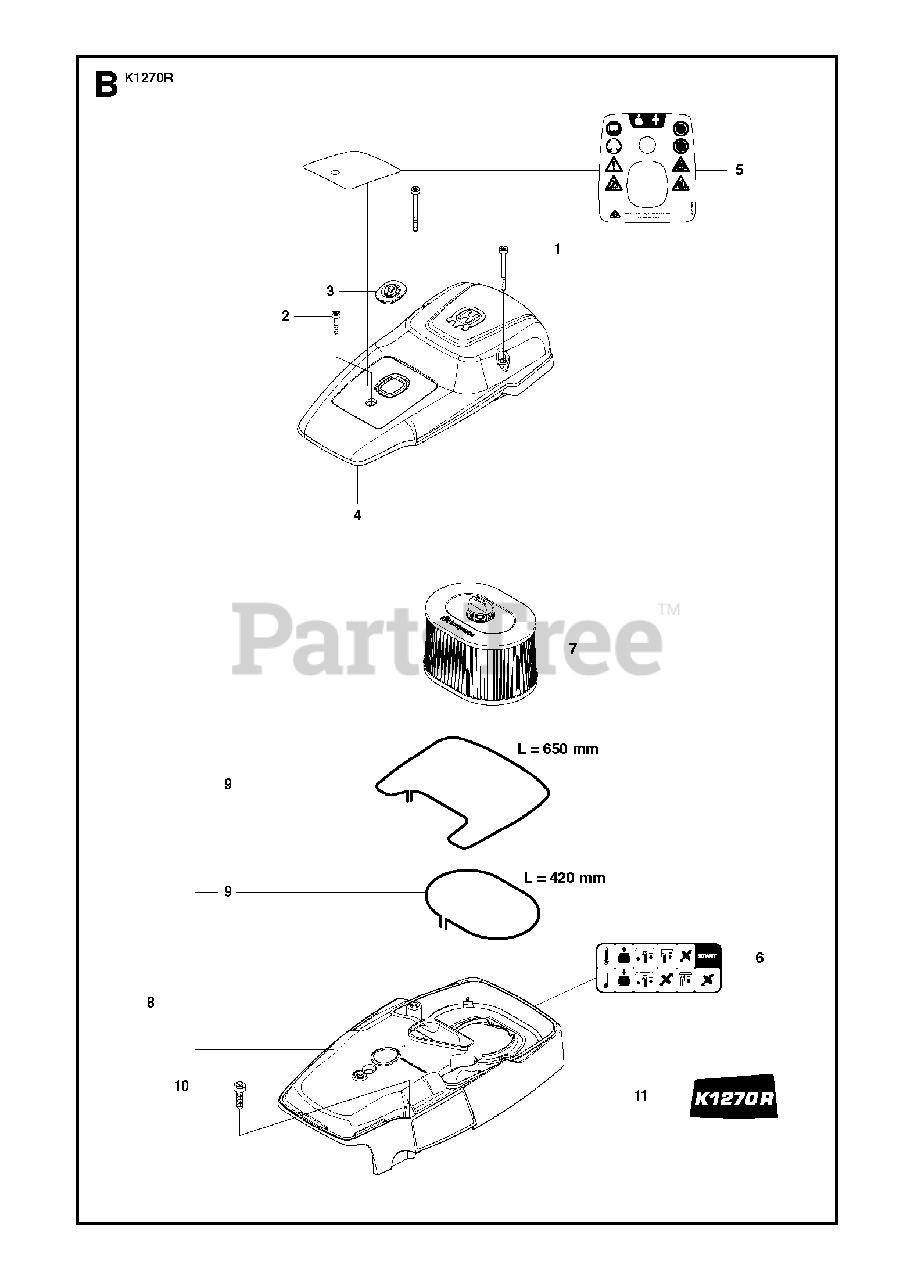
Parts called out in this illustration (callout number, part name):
1	SCREW ITXSCM
2	SCREW ITXSCM
7	AIR FILTERStandard
8	CYLINDER COVERIncl. 9
10	SCREW ITXSCM
